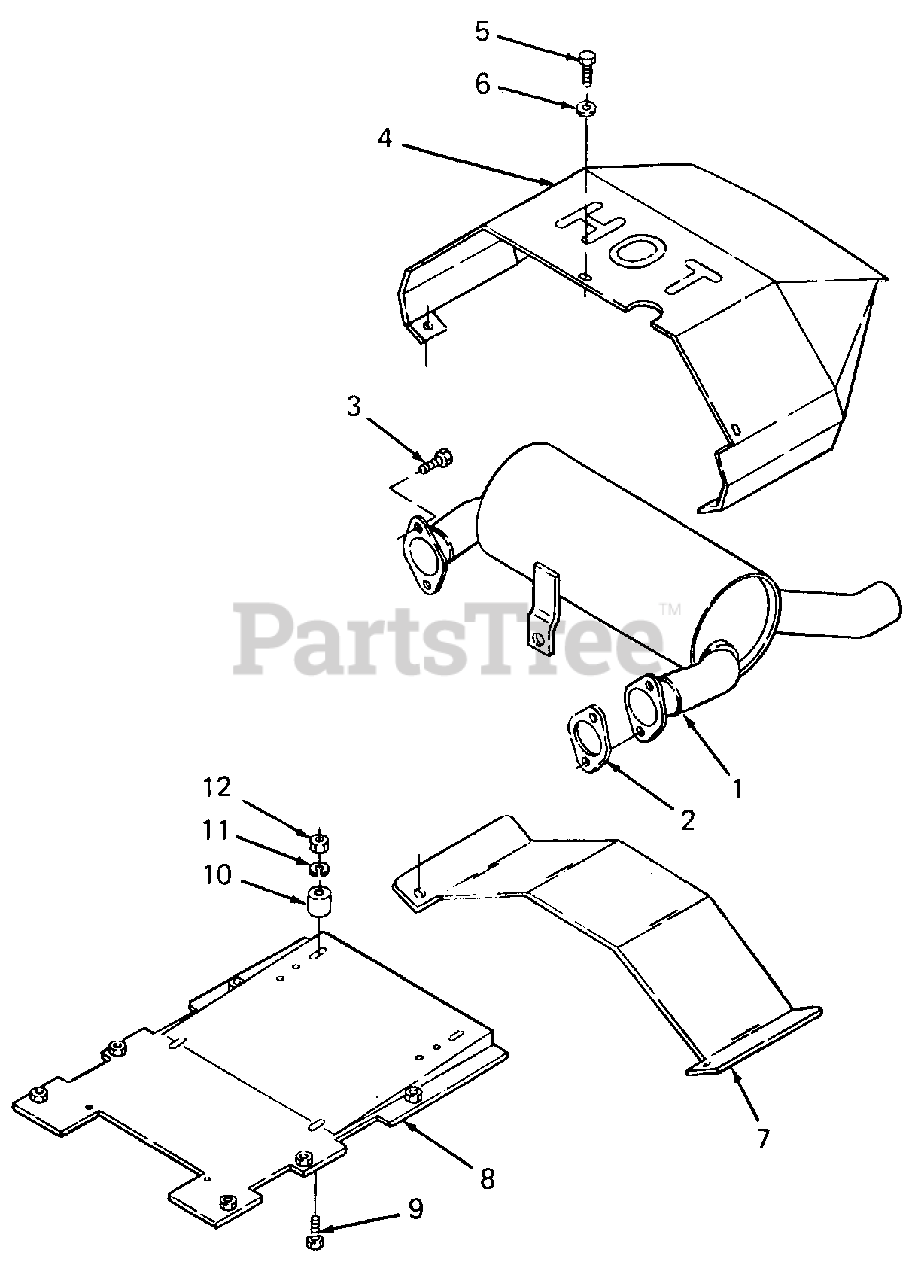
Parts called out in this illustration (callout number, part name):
2	Gasket, Exhaust
3	Screw, Sems
4	Ducting, Muffler
5	Bolt, Hex, M6-1.0 X 10 mm Lg GR5
6	Washer, Flat, .281 X .50 X .063 Thk
7	Shield, Muffler Heat
9	Screw, Hex Cap, 5/16-18 X 3.25 Lg GR5
11	Washer, Lock, 5/16
12	Nut, Hex, 5/16-18
